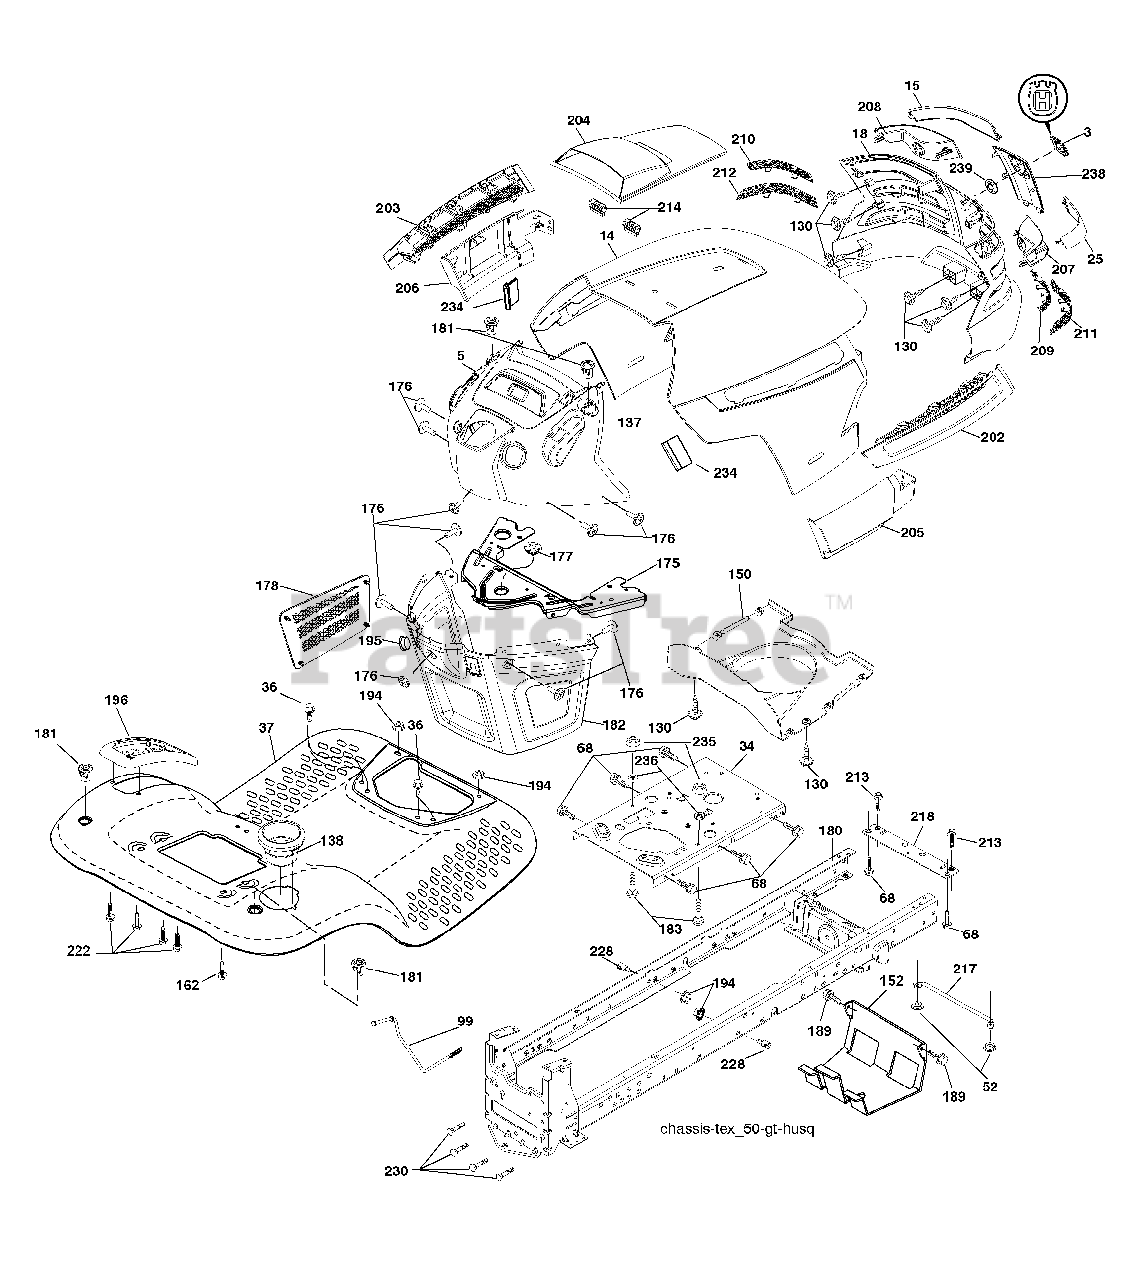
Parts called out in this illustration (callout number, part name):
3	Logo
14	Hood
18	Grille Asm.
34	Plate Engine
36	Screw 5/16-18 x 3/4
37	Fender
52	Nut Lock 5/16-18
68	Screw 5/16-18 x 1/2
99	Rod Asm Bypass
130	Screw 10 x 3/4 Single Lead-Hex
138	Cupholder
152	Shield Browning
175	Crossmember
176	Screw 10-24 x 5/8
177	Bushing Steering
178	Cargo Net Asm.
180	Chassis
181	Bushing Mtg. Fender Crgo
182	Dash Lower
183	Bolt Fin Hex 5/16-18 unc x 1-1/4
189	Screw 5/16-18 x 3/4
194	Nut Lock Hex Flange 5/16-18
195	Plug Hole Dash Lower
196	Console Asm. Deck Lift
202	Vent Side Hood RH
203	Vent Side Hood LH
204	Vent Top Hood
205	Skirt Hood Side RH
206	Skirt Hood Side LH
209	Insert Hex Top RH
210	Insert Hex Top Lh
211	Insert Hex Bottom RH
212	Insert Hex Bottom LH
213	Bolt 5/16-18 UNC x 3/4
214	Clip Retainer Tinner
217	Rod Pivot
218	X-Piece Hood Stop
222	Screw Thdrol 1/4-20 x 5/8
228	Stud Fastner
230	Bolt Shoulder 5/16 - 18
234	Bumper Hood
235	Spacer Fender
236	Nut Lock 5/16-18 UNC
